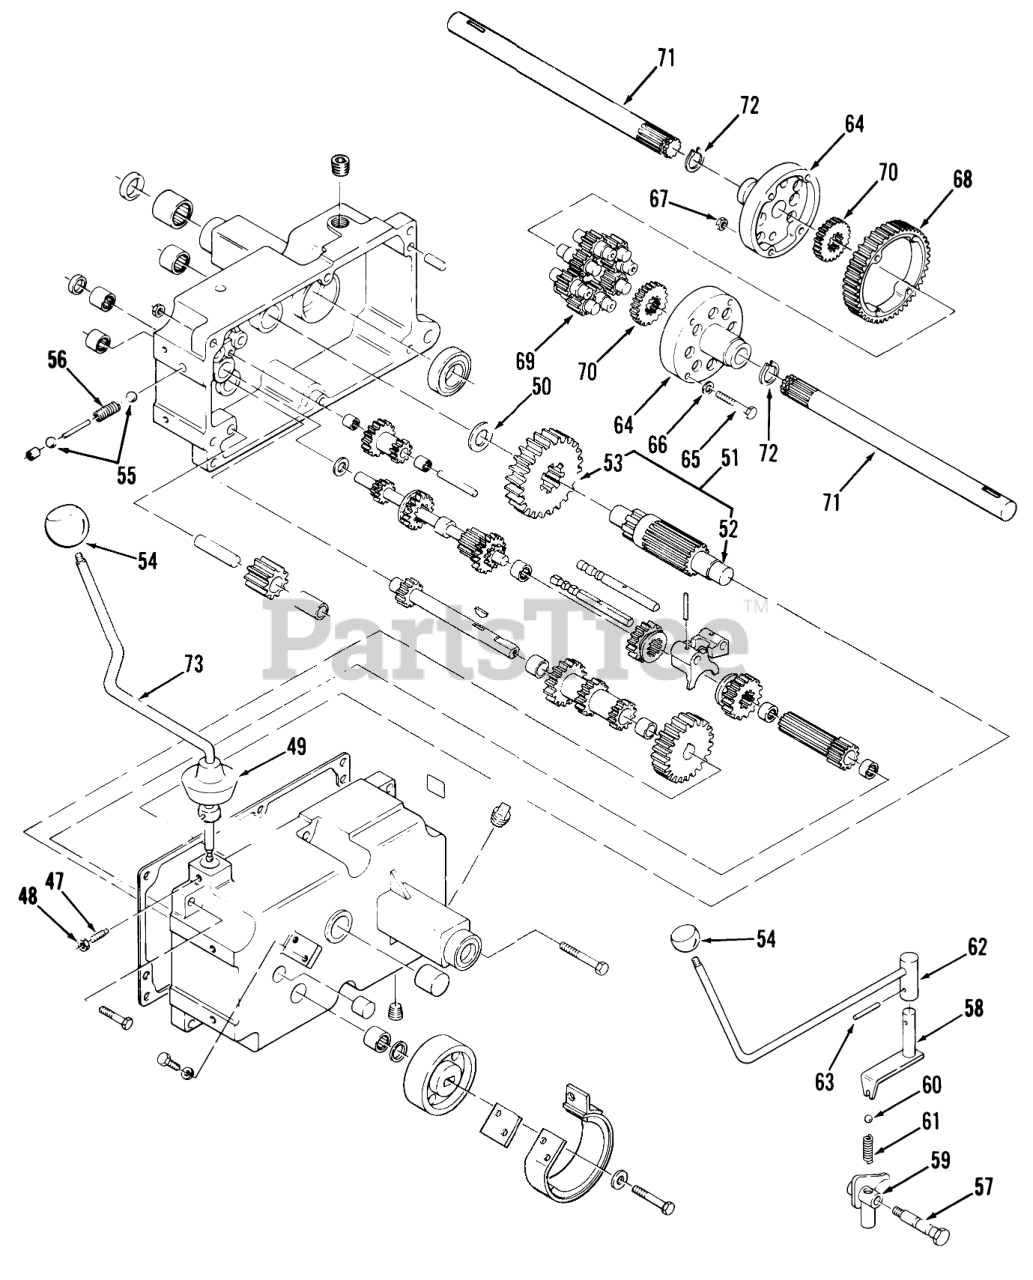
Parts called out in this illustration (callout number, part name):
47	SETSCREW
48	Nut
49	COVER-DUST
50	WASHER-THRUST
51	GEAR ASM
52	PINION SHAFT
54	SHIFT KNOB
55	BALL-DETENT
56	SPRING-SHIFT STOP
57	BOLT-DETENT
58	SHIFT ASM
59	Shift Fork
60	BALL-DETENT
61	SPRING-SHIFT STOP
62	Shift Lever HI-Low Range
63	PIN-SPIROL
64	DIFFERENTIAL END CAP
65	BOLT-HEX
66	WASHER
67	Nut
68	GEAR-DIFFERENTIAL RING, 43T
69	GEAR-PINION, 11T
70	GEAR-AXLE DIFFERENTIAL
71	AXLE-REAR
72	RING-SNAP
73	Gear Shift Lever
